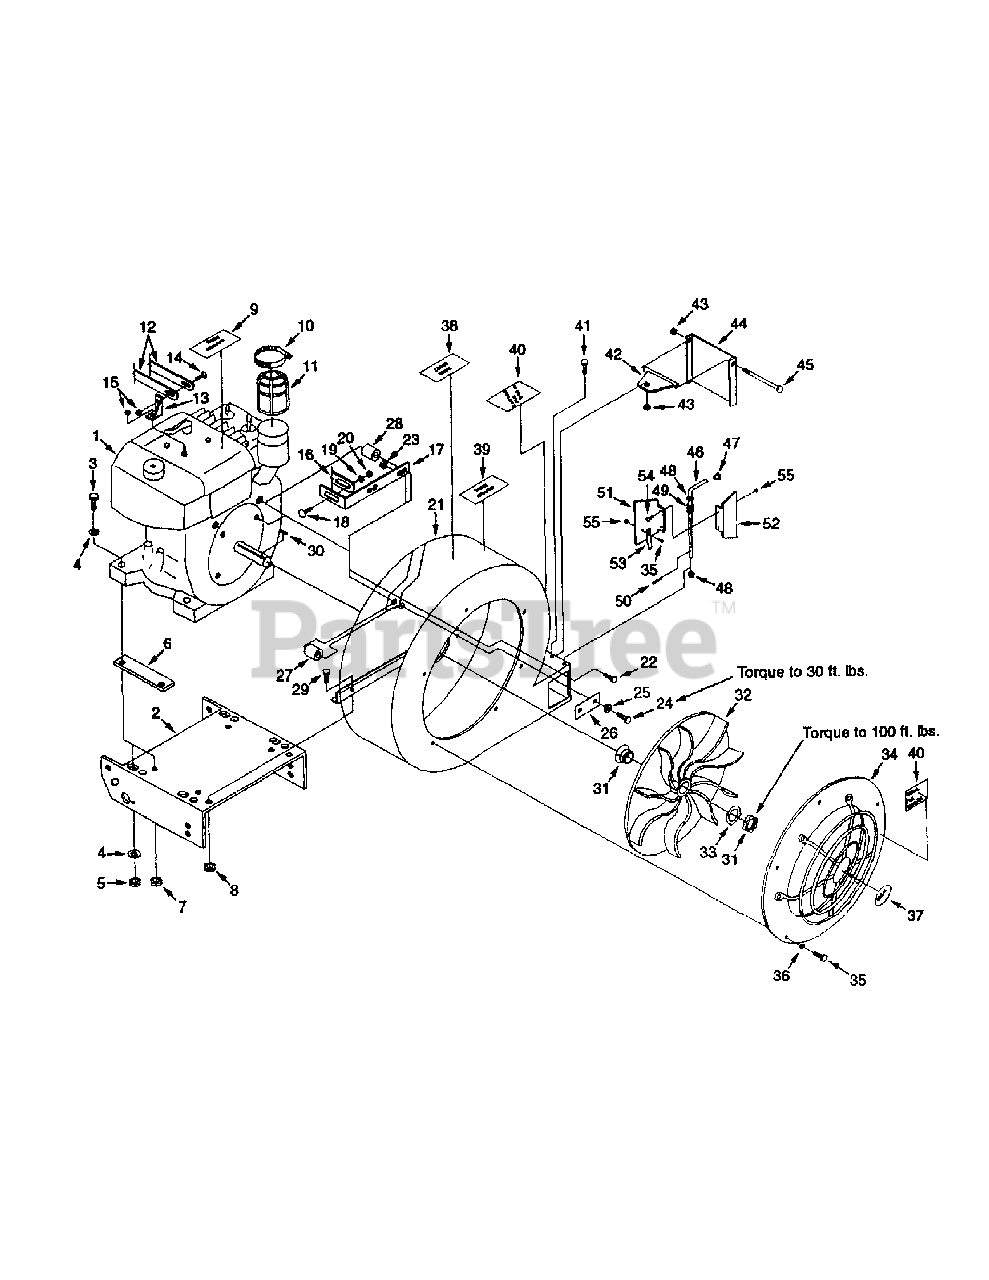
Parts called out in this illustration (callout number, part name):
1	Engine, 5hp Briggs & Stratton
2	Base Plate, Engine
3	Cap Screw, 5/16-18 x 1-3/4 Hex Head
4	Flat Washer, 5/16 SAE
5	Hex Nut, 5/16-18 Side Lock
6	Riser Plate, Engine
7	Hex Nut, 5/16-18 Side Lock
8	Hex Nut, 5/16-18 Side Lock
9	Decal Warning Label
10	Clamp, Muffler Guard
11	Muffler Guard
12	Center Brace, Offset
13	Pivot, Center Brace
14	Carriage Bolt, 5/16-18 x 3/4
15	Hex Nut, 5/16-18 Side Lock
16	Center Brace
17	Center Support
18	Carriage Bolt, 5/16-18 x 3/4
19	Flat Washer, 5/16 SAE
20	Hex Nut, 5/16-18 Side Lock
21	Fan Housing
22	Cap Screw, 3/8-16 x 1 Hex Head
23	Hex Nut, 3/8-16 Stover Lock
24	Cap Screw, 5/16-24 x 3/4 Hex Head
25	Lock Washer, 5/16
26	Strap, Housing Lock
27	Housing Spacer
28	Spacer
29	Cap Screw, 5/16-18 x 3/4 Hex Head
30	Key, 1/4 x 1/4 x 1-1/8
31	Fan Bushing/Hex Nut
32	Fan
33	Lock Ring, Fan Bushing
34	Front Guard
35	Machine Screw, #8-32 x 3/8 Round Head
36	Lock Washer, #10 External Tooth
37	Decal, Stop First/Then Lift
38	Decal, MTD
39	Decal, Caution Procedure
40	Decal, Danger Fan
41	Cap Screw, 1/4-20 x 3/4 Hex Head
42	Hinge Bracket
43	Hex Nut, 1/4-20 x 3/4 Hex Head
44	Deflector Plate
45	Cap Screw, 1/4-20 x 5 Hex Head
46	Handle, Front Door
47	Crutch Tip
48	Brass Bushing
49	Spring, Deflector
50	Cotter Pin, 3/32 x 3/4
51	Plate, Deflector Inside
52	Plate, Deflector Outside
53	Latch, Front Door
54	Machine Screw, #8-32 x 3/4 Round Head
55	Hex Nut with Washer, #8-32
